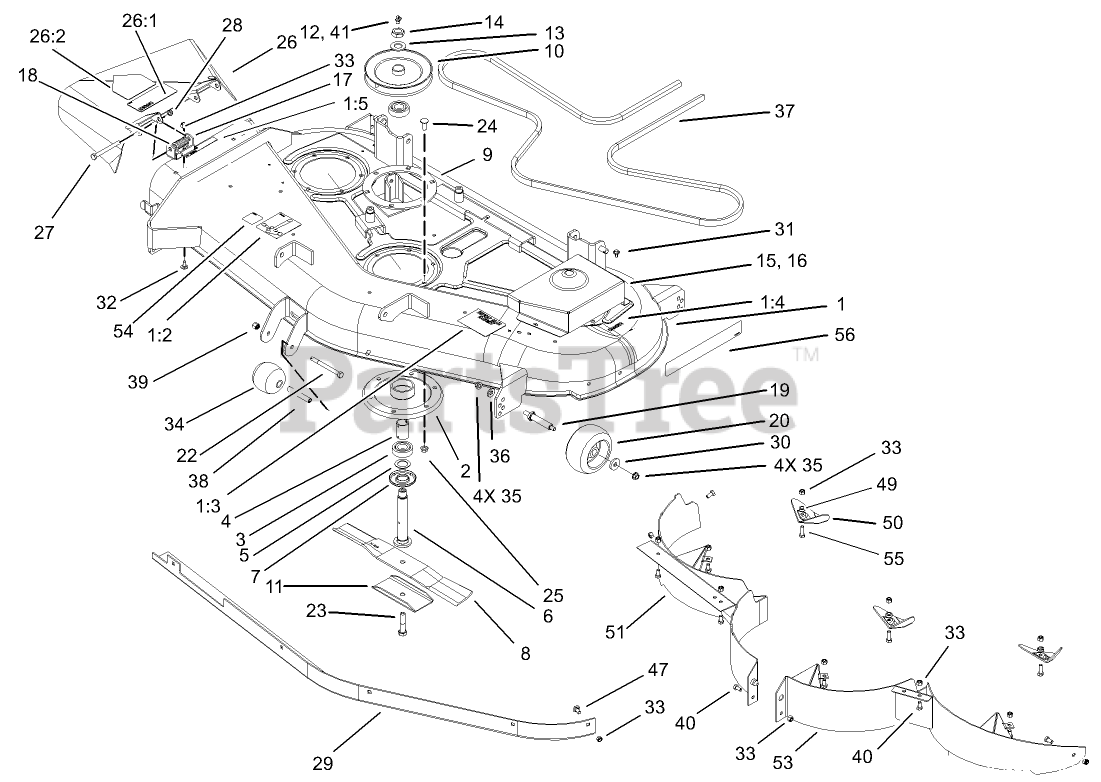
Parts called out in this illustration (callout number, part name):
1:2	DECAL-ROUTING, BELT
1:3	DECAL-ANTI SCALP
1:4	DECAL-DANGER
1:5	DECAL-DANGER
3	BEARING-BALL
4	SPACER-BEARING
5	WASHER-WHEEL
6	SHAFT-SPINDLE
7	SHIELD-BEARING
8	BLADE-18", RECYCLER
10	PULLEY/HUB ASM
11	STIFFENER-BLADE
12	FITTING-GREASE
13	WASHER-FLAT
14	NUT-JAM
16	COVER-BELT, RH
17	BRACKET-PIVOT
18	SPRING
22	SCREW-HH
23	SCREW-BLADE
24	SCREW-CARR
25	NUT-HF
26:1	DECAL-DANGER
26:2	DECAL-DANGER
27	SCREW-HH
28	NUT-HEX
30	WASHER
31	SCREW-HHFTF
32	SCREW-CARR
33	NUT-LOCK, NI
34	ROLLER
35	NUT-HHF, WHIZ
36	WASHER-BELLEVILLE
37	BELT-DECK
38	TUBE-SPACER, WHEEL
39	NUT-LOCK, NI
40	SCREW-HH
41	FITTING-GREASE
49	SPACER
50	PLATE-KICKER
51	RIGHT BAFFLE ASM
52	SCREW-HH
53	LEFT BAFFLE ASM
55	SCREW-HH
56	DECAL-DECK
